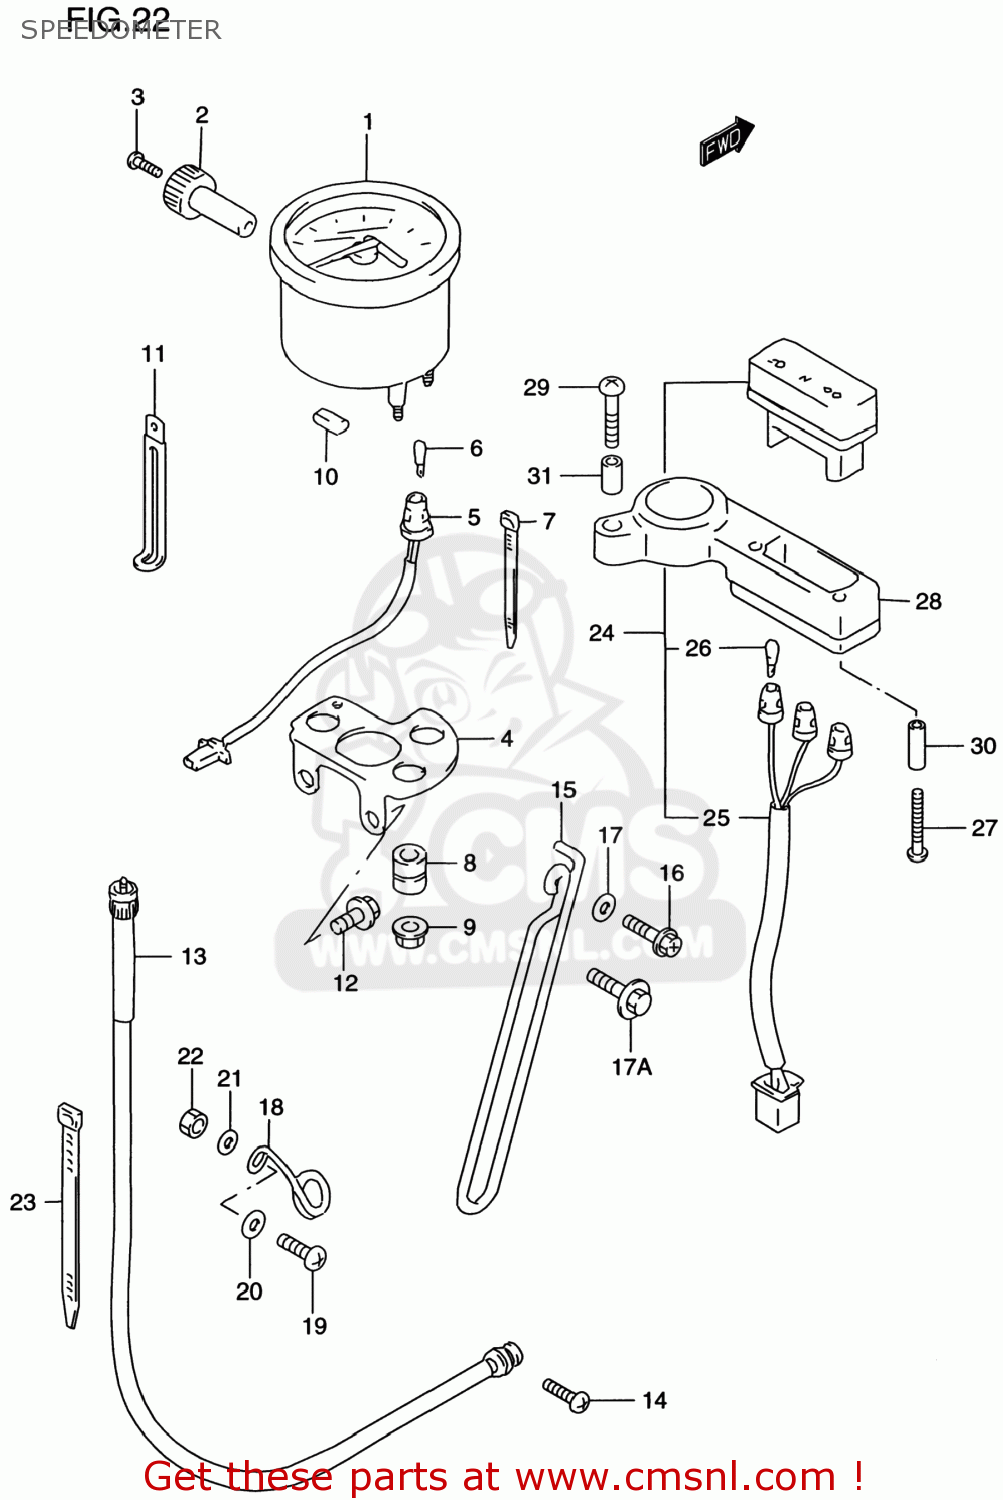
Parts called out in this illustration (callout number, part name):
1	SPEEDOMETER
2	KNOB,TRIP
3	SCREW,TRIP KNOB
4	BRACKET,METER
5	SOCKET
6	BULB(12V1.7W,T6.5)
7	CLAMP
8	CUSHION
9	NUT
10	CUSHION
11	CLAMP(L:97)
12	BOLT
13	CABLE ASSY,SPEEDOMETER
14	SCREW
15	GUIDE,METER CABLE NO.2
16	SCREW
17	WASHER(6.5X20X1.6)
17A	BOLT(6X20)
18	GUIDE,METER CABLE NO.3
19	SCREW
20	WASHER
21	WASHER
22	NUT 6MM
23	CLAMP(L:95)
24	BOX ASSY,PILOT LAMP
25	SOCKET & CORD
26	BULB(13.5V,2W,A7427)
27	SCREW
28	HOLDER,PILOT BOX
29	SCREW(6X25)
30	SPACER(4.5X6.5X25)
31	SPACER(6.1X8X15.5)
